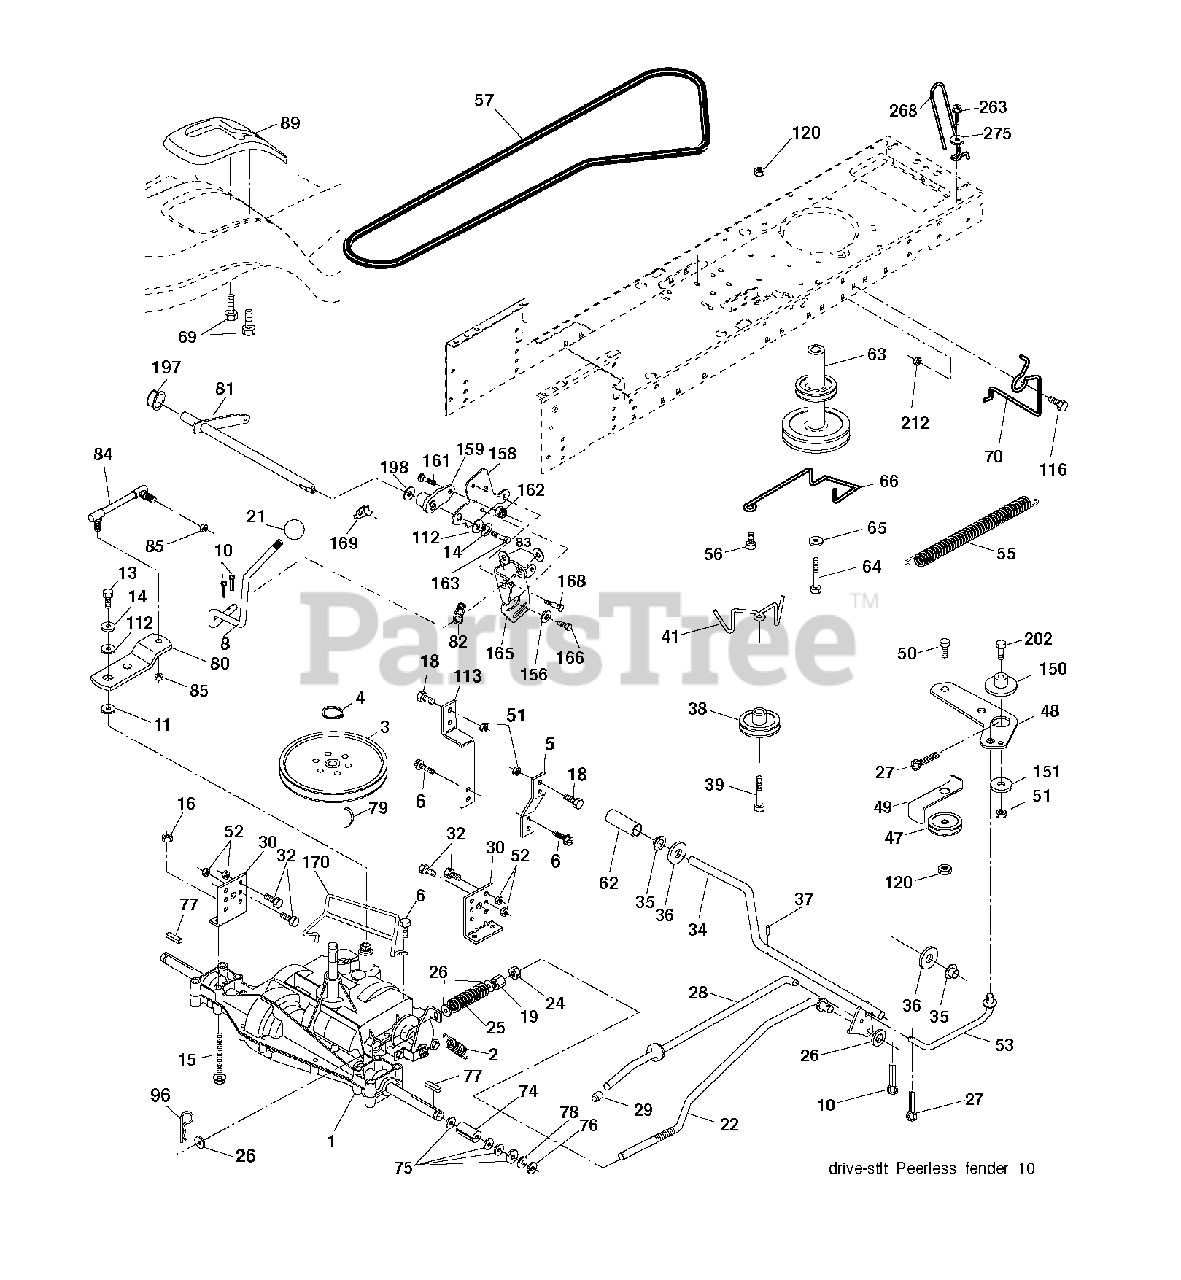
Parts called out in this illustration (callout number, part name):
2	SPRING,BRAKE RETURN
3	PULLEY TRANS
4	RETAINING RING LT
5	STRAP TORQUE
6	SCREW 5/16"
8	ROD SHIFT FENDER ADJUST LT
10	PIN COTTER
11	WASH-SHFT PLT LT
13	BOLT 1/4-28X3/4
14	LOCKWASHER
15	BOLT HEX 5/16-18 GR 5
16	NUT.71038.31-18.HEX.NYLOCK
19	NUT
21	KNOB T (1/2-HOLE)
22	ROD BRAKE
24	NUT
25	SPRING ROD LT
27	COTTER PIN
28	ROD, PARKING BRAKE
29	PLUNGER CAP
30	BRKT, MOUNT TRNSAXLE
32	BOLT
34	SHAFT, FOOT PEDAL
35	BEARING.NYLON
36	WASHER LT
37	DRIVE PIN
38	PULLEY IDLER COMPOSITE
41	KEEPER, BELT IDLER
47	IDLER PULLEY
48	BELLCRANK, CLUTCH
49	RETAIN BELT
50	BOLT.3/8-16X1.50
51	LOCKNUT
52	LOCKNUT
53	LINK.CLUTCH.7.66.2005
55	SPRING, RETURN LT
56	SCREW.3/8-16
57	BELT, V GROUND DRIVE 95 25
62	PEDAL COVER T
63	ENGINE PULLEY
64	BOLT HEX 7/16-20X4-1/4"
65	LOCKWASHER
66	KEEPER BELT ENGINE
69	SCREW.HI-LO.CONSOLE
70	KEEPER BELT ENG
74	SPACER AXLE
76	E-RING LT
77	SQUARE KEY
80	ARM SHIFT
82	SHIFT SPRING
83	WASHER
85	NUT LOCK CENTER 1/4 -28 FNTHD
96	RETAINER M
112	WASHER LT
113	STRAP TORQUE LH LT
116	BOLT D
120	NUT LOCK FLG 3/8-16 UNC
150	SPACER, RETAINER
151	WASHER 12/32X2X10GA
156	WASHER.SRRTD.5/16
158	BRACKET
159	HUB.SHIFT
161	BOLT
162	NUT.CROWNLOCK.1/4
165	RP BRACKET
168	BOLT.SHOULDER.5/16-18X
169	PLATE.FASTENING.CROSS.SHAFT
170	KEEPER BELT T/A
197	NYLINER SNAP 5/8" ID
198	WASHER.NYL.7/8IDX.105"HYD CR
202	BOLT
212	NUT
263	SCREW, 3/8-16X3/4
275	WASHER
